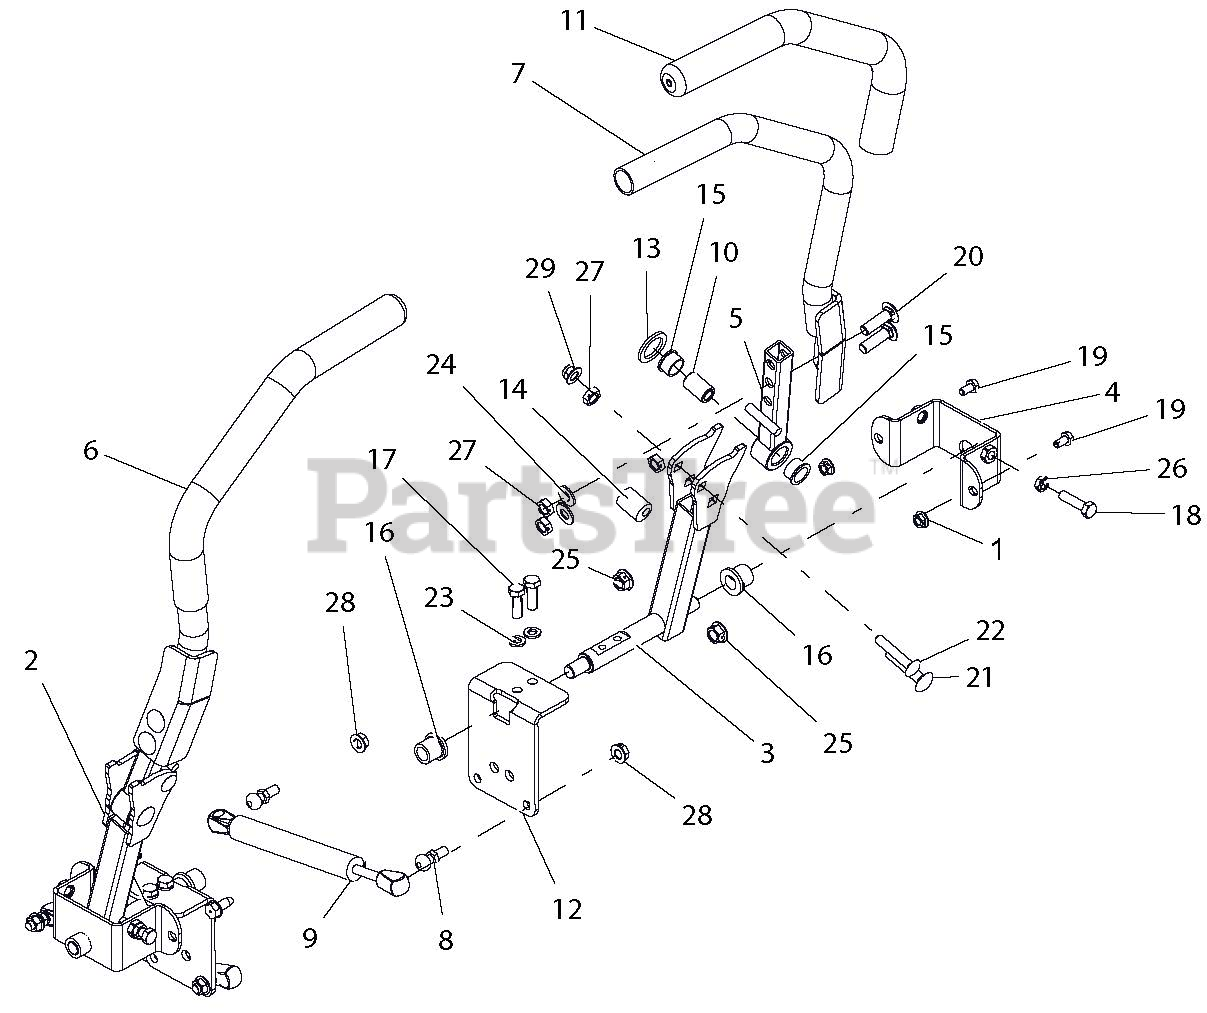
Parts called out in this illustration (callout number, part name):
1	@NUT-LK-CTR-FLG .25-20 YWZC
2	WLDMT, RT LOWER STEERING ARM
3	WLDMT, LEFT LOWER STEERING ARM
4	BRKT, STEERING SUPPORT
5	WLDMT, UPPER CONTROL ARM
6	WLDMT, STEERING HANDLE RH
7	WLDMT, STEERING HANDLE LH
8	STUD- BALL
9	DAMPER, STABILUS
10	SPACER, .375X.625X.970 (PM)
11	GRIP, HANDLEBAR 15" FOAM
12	BRKT, STEERING
13	WASHER, FRICTION .875X1.25X.10
14	BSHG, ECCENTRIC .328X.750X.970
15	BSHG-FLG, .625X.75X.450X.875
16	BSHG-FLG .515X.750X.745X1.00NY
17	BLT-HEX .31-18X1.00 GR8 YWZC
18	@BLT-HEX .31-18X1.25 GR5 YWZC
19	@BLT-HEX .25-20X.50 GR5 YWZC
20	BLT,RHSSN .38-16X1.25 G5 BFP
21	BLT,RHSSN .38-16X1.75 G5 BFP
22	BLT,RHSSN .31-18X1.75 G5 BFP
23	@WSHR-LK .31X.078 REG YWZC
24	@WSHR-FL-STL.406X.812X.065 YWZ
25	NUT-LK-CTR-FLG .38-16 YWZC
26	NUT- JAM .312-18 YWZC
27	@NUT-LK-CTR-JAM .375-16 YWZC
28	@NUT-LK-TOP-FLG .31-18 YWZC
29	@NUT-LK-NYL-FLG .31-18 YWZC
30	@SCR-TAP .31-18X.75 HWH TR YWZ
